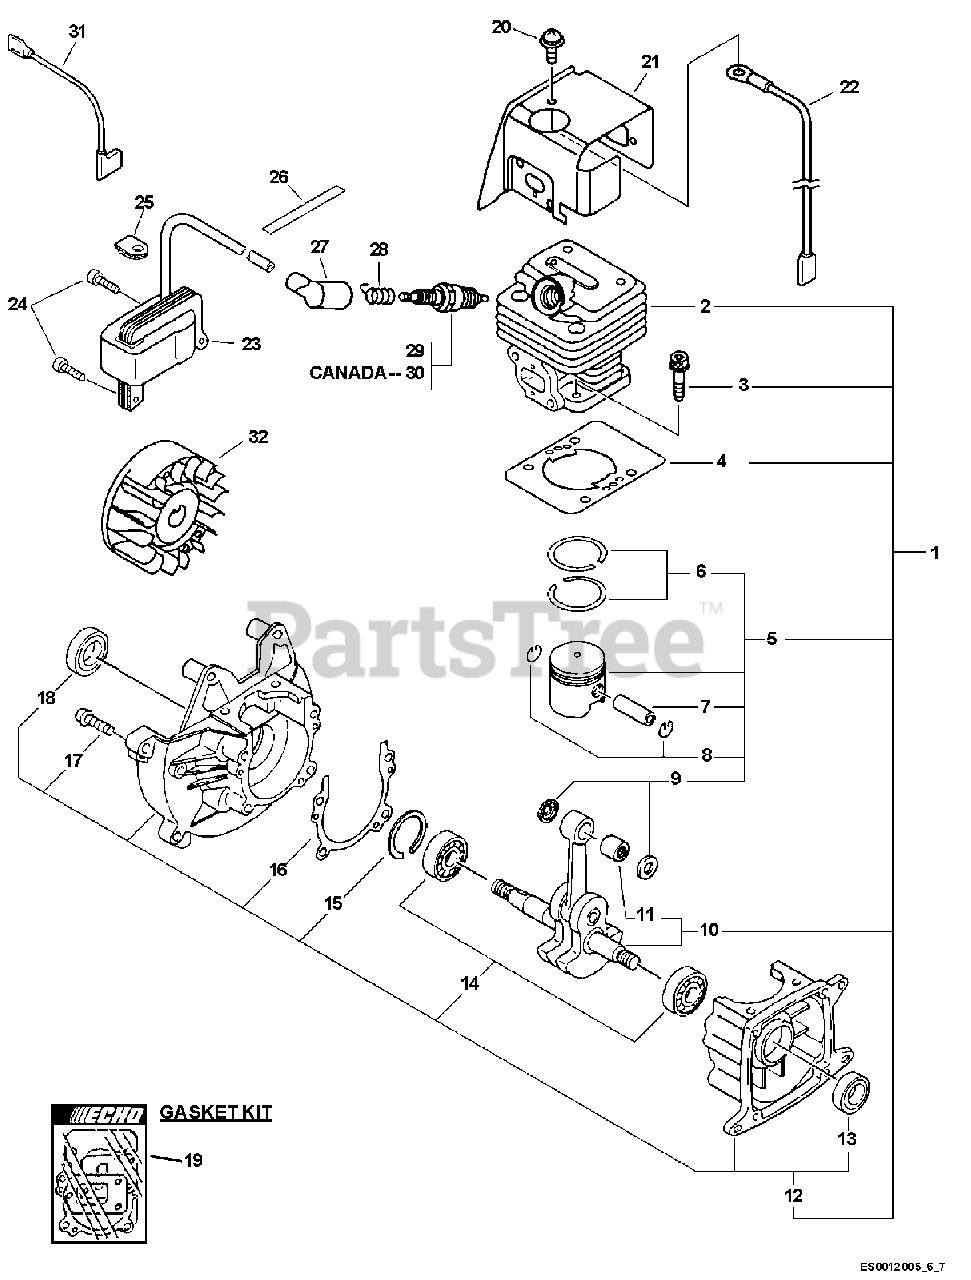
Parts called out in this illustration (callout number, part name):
1	SHORT BLOCK
2	CYLINDER
3	BOLT 5×22
4	GASKET, CYLINDER
5	PISTON KIT
6	RING, PISTON
7	PIN, PISTON 8
8	RING, SNAP
9	WASHER, THRUST
10	CRANKSHAFT ASSY
11	BEARING, NEEDLE 8
12	CRANKCASE KIT
13	SEAL, OIL 12
14	BEARING, BALL 6001
15	RING, SNAP 28
16	GASKET, CRANKCASE
17	BOLT 5×25
18	SEAL, OIL 12
19	GASKET KIT
20	SCREW 5×10
21	COVER, CYLINDER
22	LEAD - GROUND
23	COIL, IGNITION
24	BOLT 5×16
26	LABEL, SPARK PLUG - BPM8Y
27	CAP, SPARK PLUG
28	TERMINAL, SPARK PLUG
29	SPARK PLUG - BPM8Y
30	SPARK PLUG - BPMR8Y
31	LEAD - IGNITION
32	FLYWHEEL
